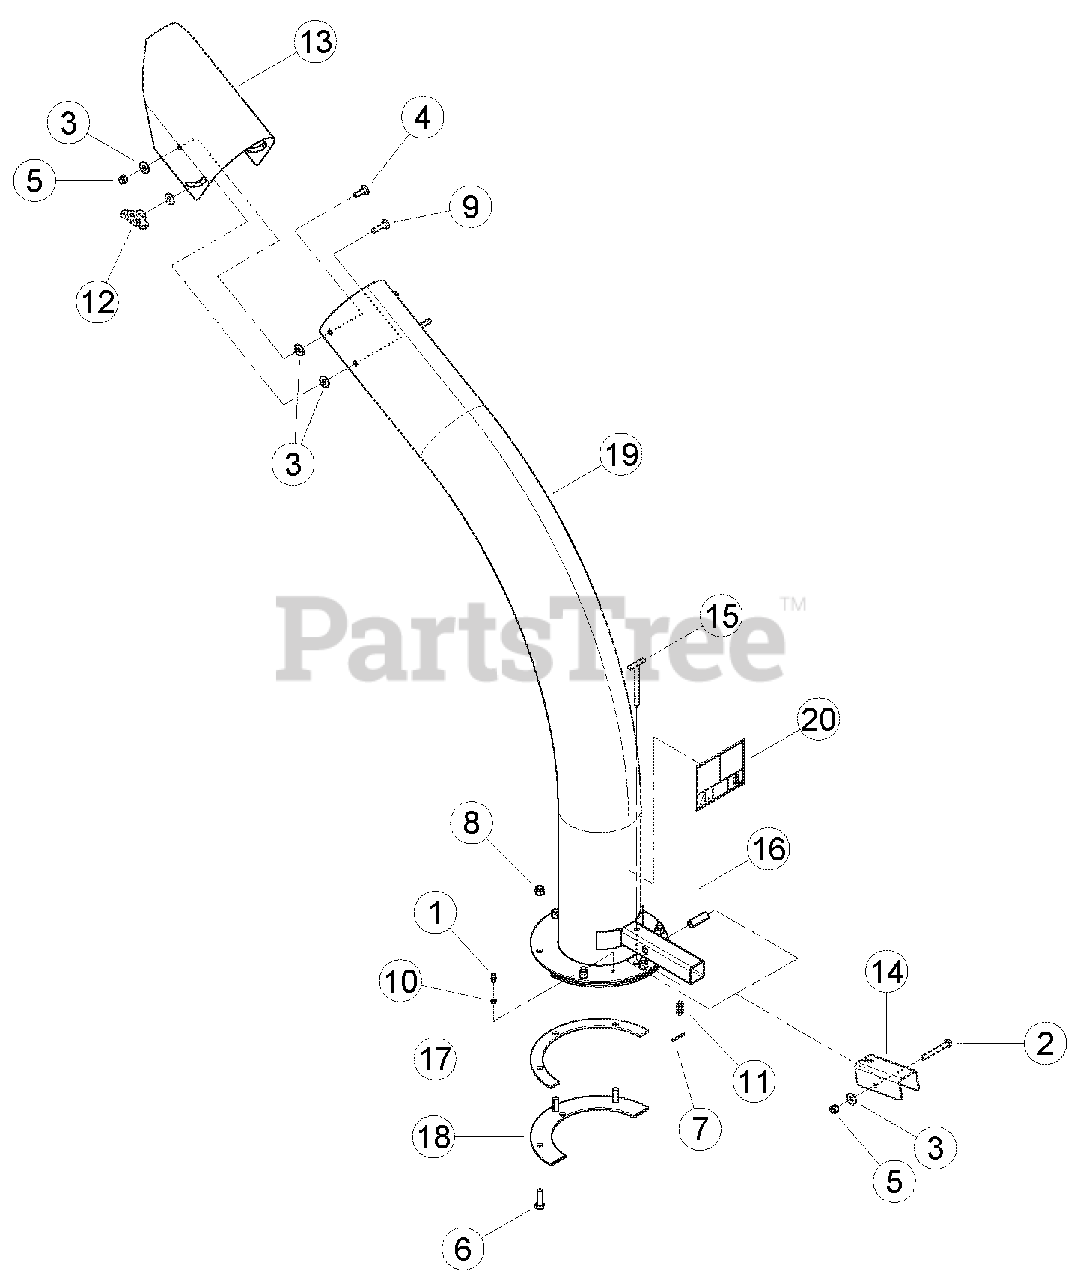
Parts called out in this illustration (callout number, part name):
1	FITTING, 1/4 SELF-TAP GREASE
2	BOLT, 5/16 X 2-1/2 HEX HD GR5 ZP
3	WASHER, 5/16 FLAT ZP
4	BOLT, 5/16 X 1 CRG GR5 ZP
5	NUT, 5/16 NE NYLOCK ZP
6	BOLT, 3/8 X 1-1/4 HEX HD GR5 ZP
7	PIN, 1/8 X 1.00 COTTER ZP
8	NUT, 3/8 NE NYLOCK ZP
9	BOLT, 5/16 X 1-1/4 CRG GR5 ZP
10	WASHER, .254 X .400 X .048 FLAT
11	SPRING, LOCK COMPRESSION
12	KNOB, 5/16-18 UNC TEE W/LOCKING INSERT
13	DEFLECTOR, BLOWER-VAC DISCHARGE
14	LEVER, DISCHARGE LOCK
16	TUBE, DISCHARGE LOCK PIVOT
17	SPACER, DISCHARGE PIVOT
18	RING, DISCHARGE CLAMP
19	ASSEMBLY, 6 INCH DISCHARGE, SERVICE PART
20	DECAL, DISCHARGE DEBRIS & LOCK
